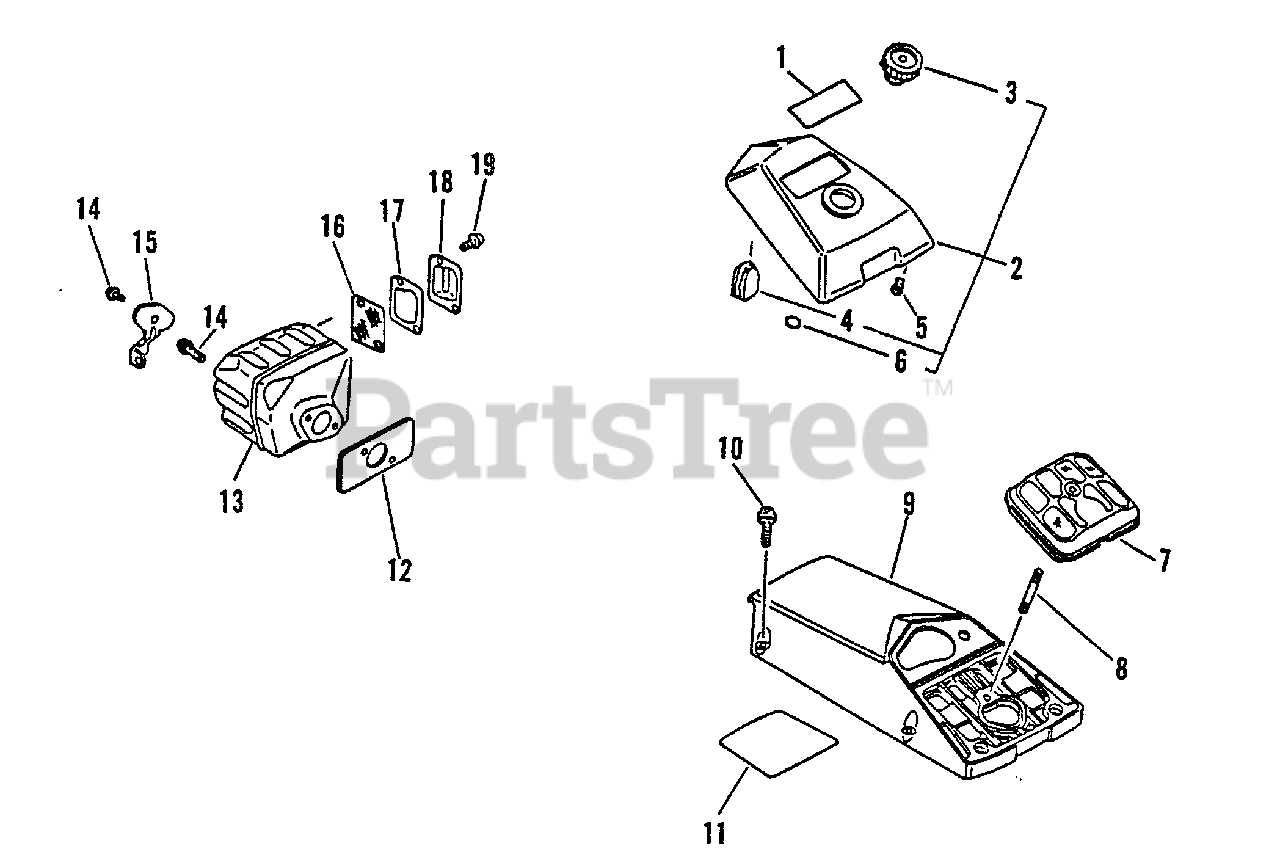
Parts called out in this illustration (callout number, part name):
1	LABEL - MODEL
2	COVER, AIR FILTER
3	THUMBNUT
6	O-RING - 11
7	FILTER, AIR
9	COVER, ENGINE
10	SCREW - 5X20
11	COVER, ENGINE
12	GASKET, EXHAUST
13	MUFFLER
14	SCREW - 5X10
15	BRACKET, MUFFLER
16	SCREEN, SPARK ARRESTOR
17	GASKET, EXHAUST
18	LID, MUFFLER
19	SCREW - 4X8
